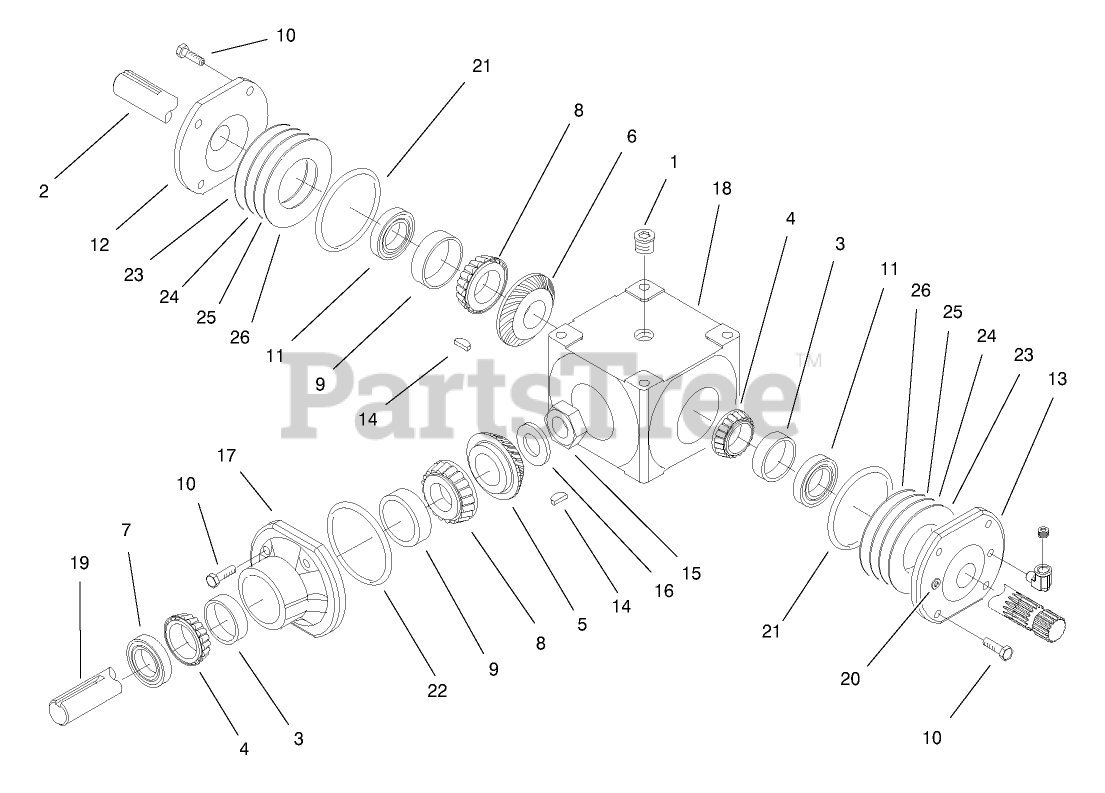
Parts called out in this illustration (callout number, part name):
2	SHAFT-CROSS
3	Bearing-Cup
4	Bearing-Cone
5	GEAR-SPIRAL, RH
6	GEAR-SPIRAL, LH
8	BEARING-CONE
9	BEARING-CUP
10	SCREW-HH
11	SEAL
12	CAP-END
13	END CAP W/ DRAIN PLUGS
14	OBS KEY
15	NUT-LOCK
16	WASHER
17	HOUSING-PINION
19	SHAFT-PINION
21	O-RING
22	O-RING
23	SHIM-GREEN (.003)
24	SHIM-BLUE (.005)
25	SHIM - BROWN (.010)
26	SHIM-YELLOW (.020IN)
